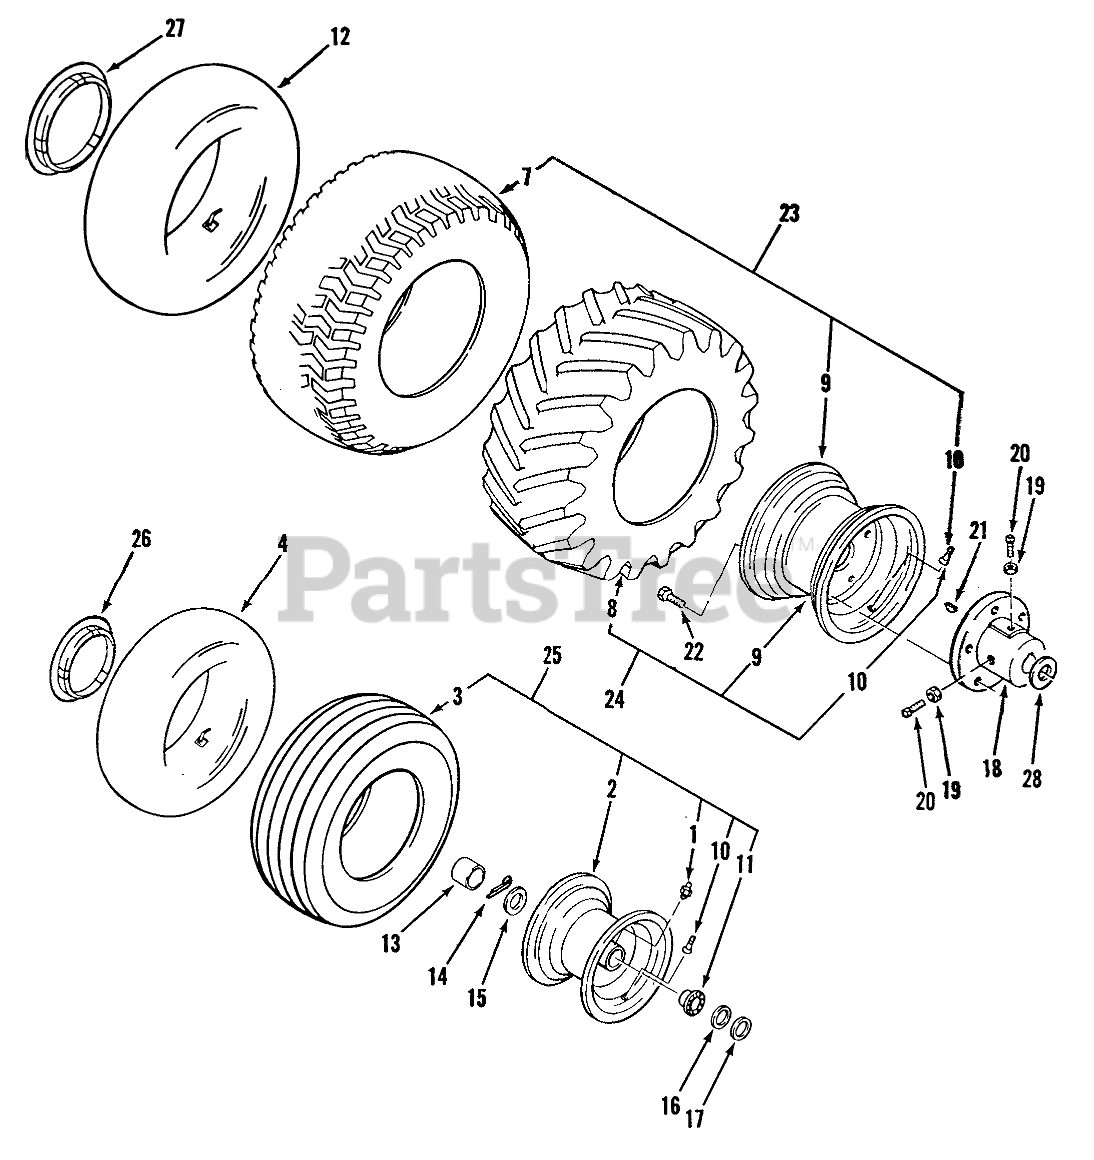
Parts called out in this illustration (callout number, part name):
1	ZERK-GREASE
2	Front Wheel (includes items 1, 10 & 11)
3	TIRE TURF SAVER 16X6.50-8
4	TUBE-INNER
7	Engine
8	Tire-Cleat, Rear
9	WHEEL
10	VALVE
11	BEARING-WHEEL
12	TUBE-INNER
13	HUBCAP
14	COTTER PIN-4
15	WASHER WHEEL
16	WASHER
17	WASHER-SHIM
18	Hub Rear
19	Nut
20	Screw-Set
21	KEY-WOODRUFF
22	Lug Nut
23	Rear Wheel & Tire Assy 416
24	ASSY WHEEL & TIRE
25	Front Wheel & Tire Assy 414, 416
26	8"-HUB CAP LOGO
27	12"-HUB CAP LOGO
28	WASHER-THRUST
